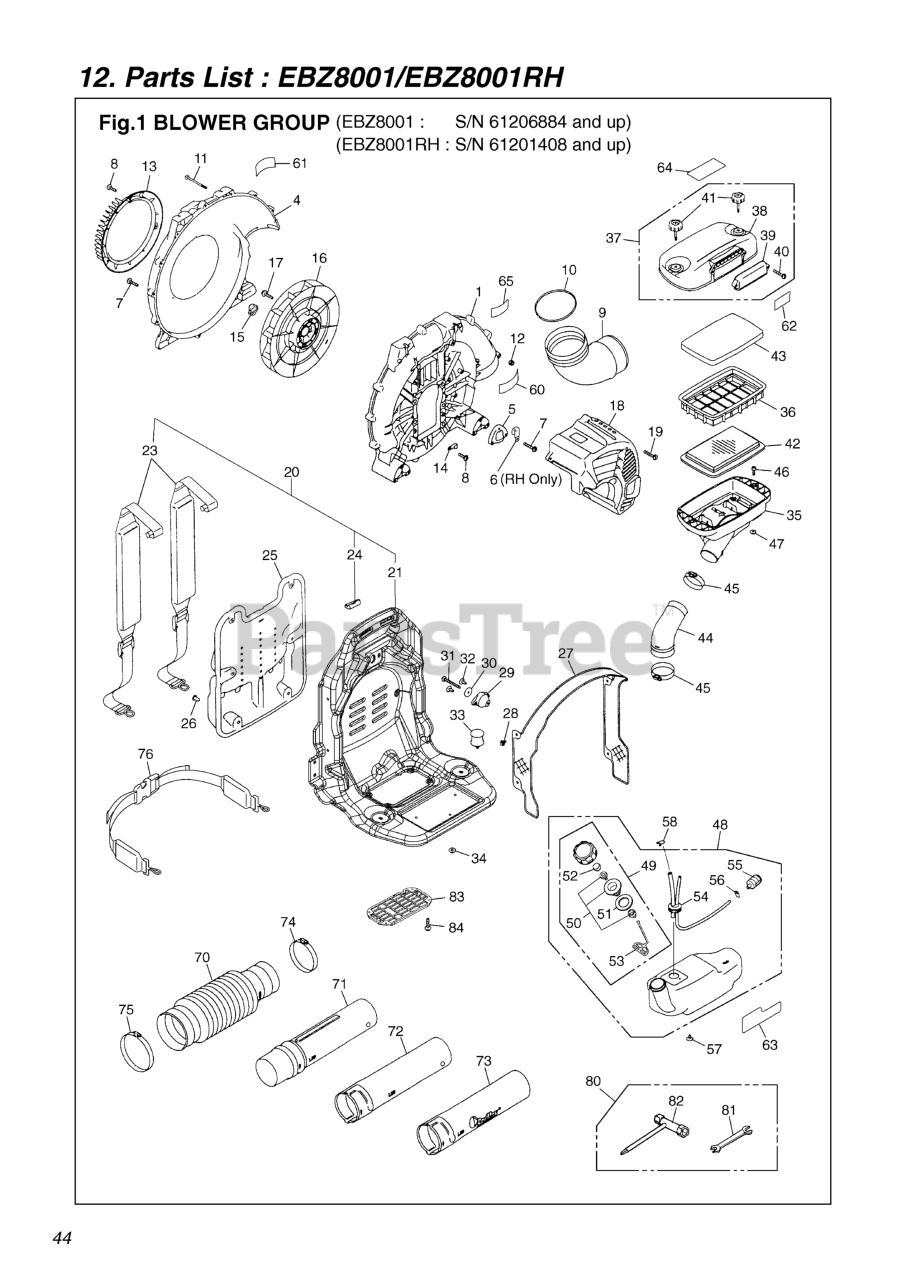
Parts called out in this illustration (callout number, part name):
1	VOLUTE CASE (REPLACES -55A3)
4	VOLUTE COVER
7	SCREW
9	ELBOW
10	O-RING
11	SCREW TORX
12	NUT (B)
13	COVER, INLET (REPLACES -55D3)
14	CLAMP (RPLS 1140-72231)
15	CAP
16	FAN (REPLACES 848-L58-5212)
17	BOLT
18	Engine Cover
19	SCREW
20	FRAME ASSY
21	FRAME
23	BAND ASSY
24	CLIP
25	PAD
26	CLIP (RPLS 3490-21320)
27	NET COMP
28	CLIP
29	DAMPER, UPPER
30	WASHER
31	BOLT, TORX
32	SCREW TORX
33	DAMPER, LOWER
34	NUT, M6
35	BODY, CLEANER
36	CASE, INNER
37	COVER ASSY
38	COVER
39	COVER
40	SCREW
41	KNOB BOLT
42	ELEMENT (PAPER)
43	ELEMENT (FOAM) (RPLS -82320)
44	HOSE
45	CLAMP
46	BOLT (USE 848-815-2000)
47	NUT
48	TANK-A
49	CAP ASSY (RPLS -85201)
50	HOLDER (REPLACES -85230)
51	PACKING
52	FILTER
53	STOPPER
54	PIPE COMP
55	FILTER ASSY
56	CLIP (REPLACES 2841-31280)
57	SCREW TORX
58	CLIP
60	LABEL, CAUTION (RPLS -31910)
61	LABEL, NET
62	LABEL, EBZ8001
63	LABEL
64	LABEL
65	LABEL, SOUND
70	FLEX HOSE
71	SWIVEL JOINT
72	PIPE, STRAIGHT
73	PIPE, END
74	CLAMP
75	CLAMP
76	BAND ASSY
80	TOOL-SET
81	SPANNER, 8 X 10 (RPLS 2540- )
83	NET
84	CLIP
